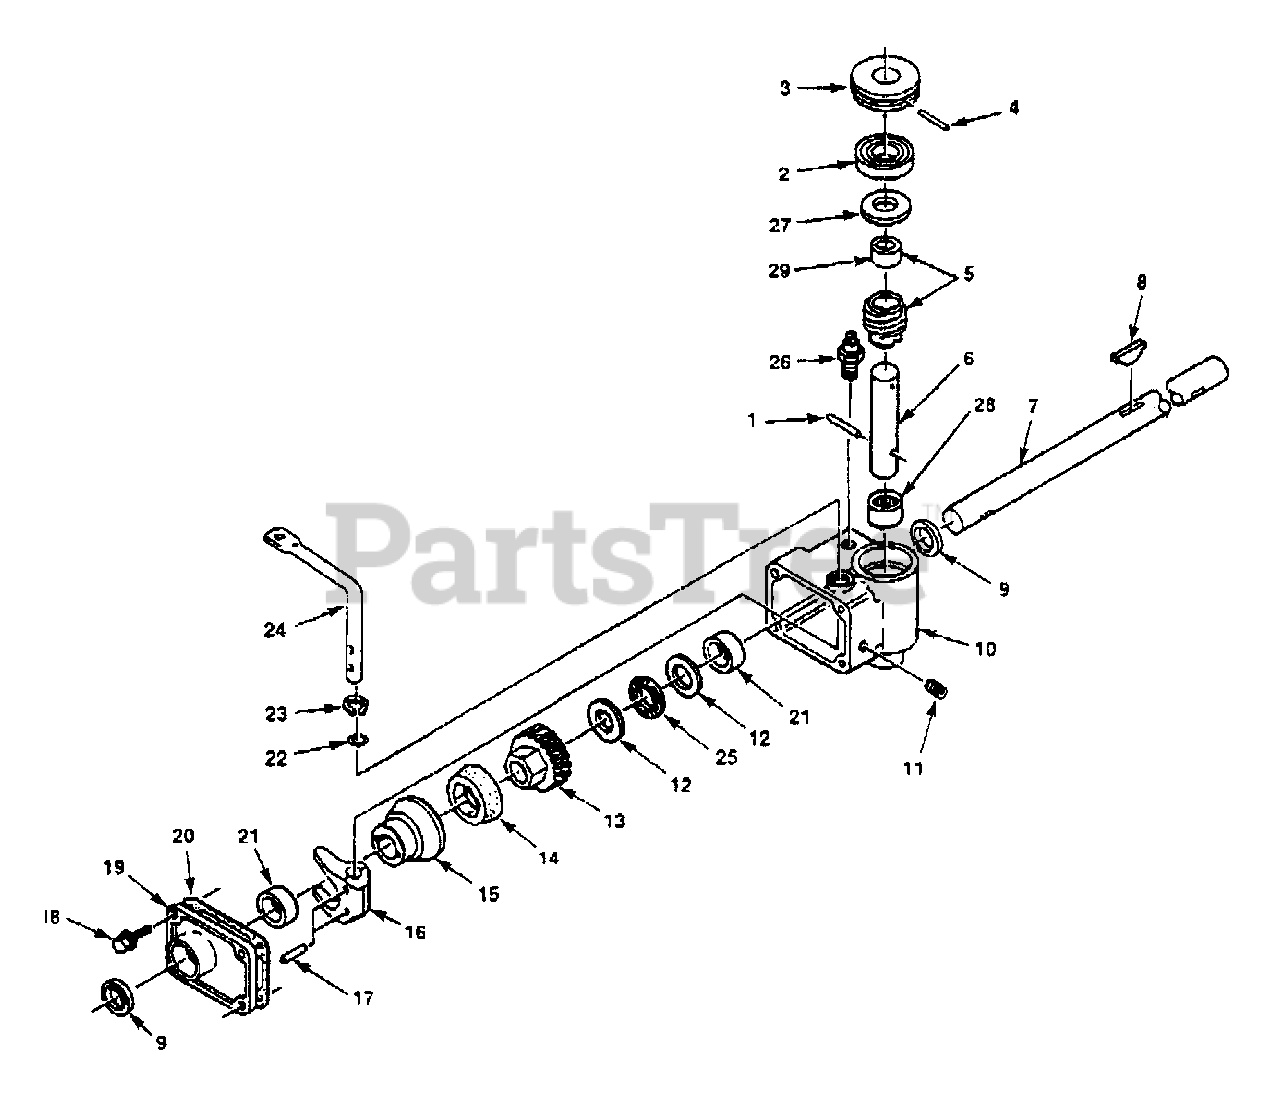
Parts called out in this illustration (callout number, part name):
2	BEARING, Ball
3	PULLEY
5	WORM & SPACER (Incl. Ref. No. 29)
6	SHAFT, Worm
7	SHAFT, Drive
10	GEAR REDUCER HOUSING ASSY. (Incl. Ref. No. 9 and 21)
12	RACE, Bearing
13	GEAR, Helical
14	CONE, Friction
15	DRUM, Clutch
16	FORK, Shift
18	SCREW, Sems Thd., 1/4-20 x 7/8"
19	COVER, Gear Box (Incl. Ref. No. 9 and 21)
21	BUSHING, Sleeve
24	LEVER, Shift
25	BEARING, Thrust
28	BEARING, Needle
